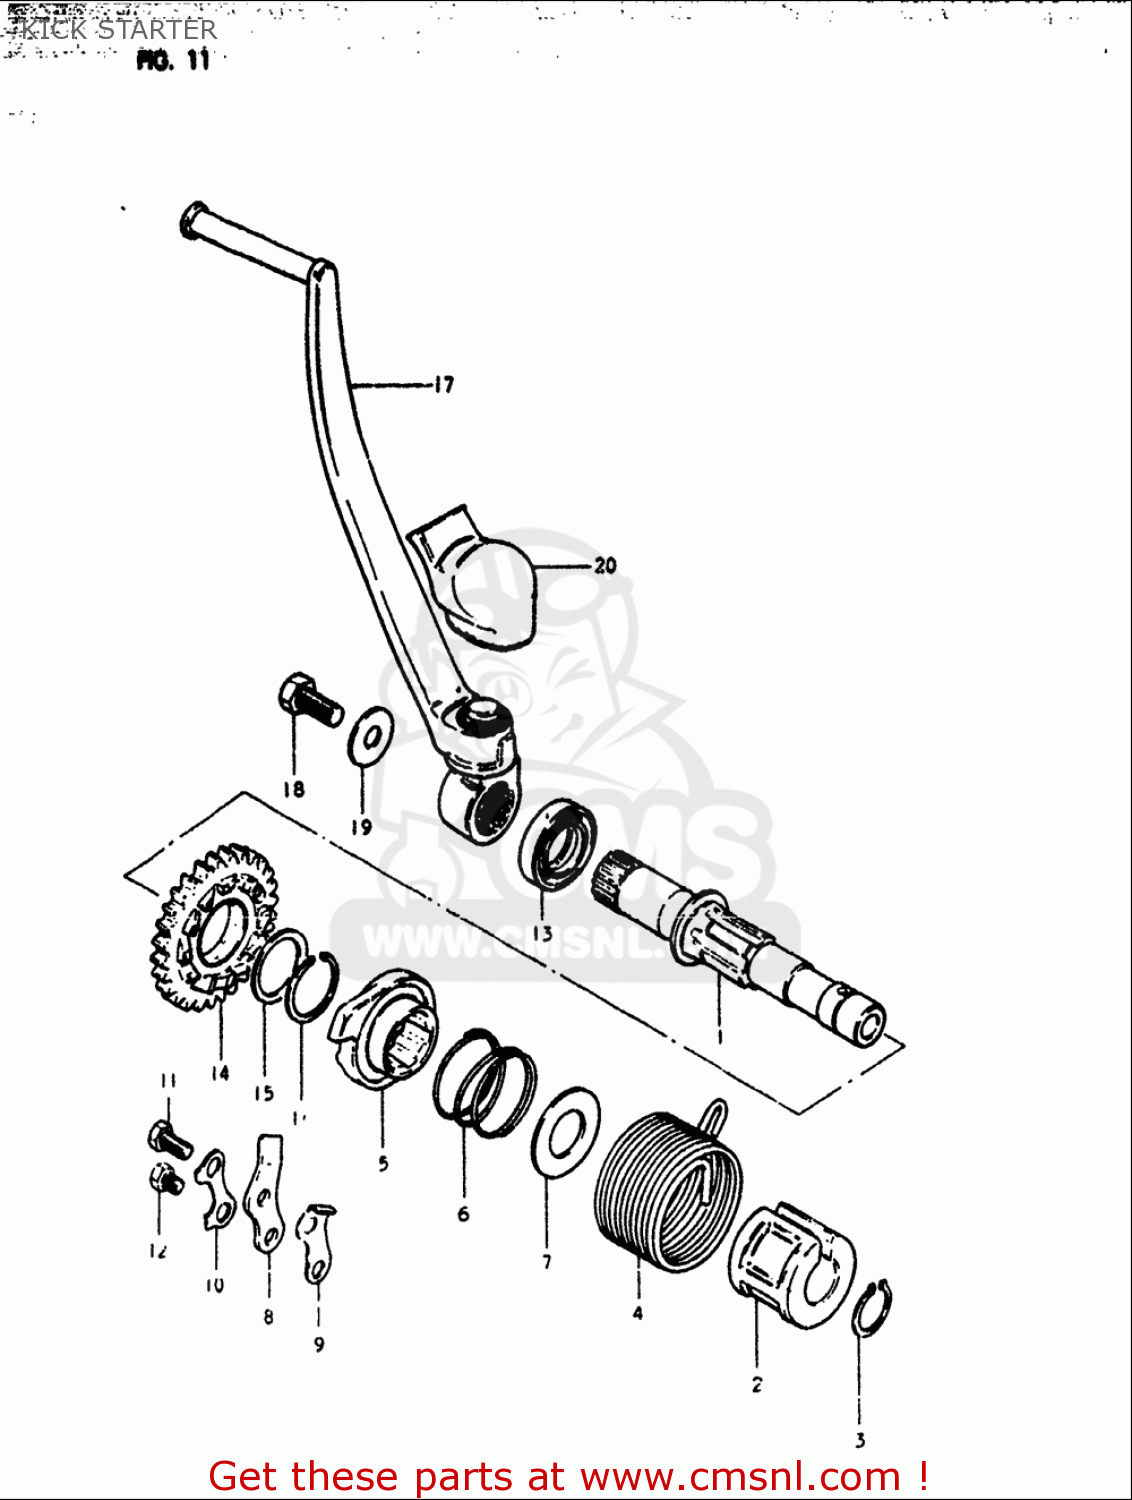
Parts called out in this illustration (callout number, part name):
1	SHAFT,KICK STARTER
2	GUIDE,KICK STARTER SFT SPRING
3	CIRCLIP
4	SPRING
5	STARTER,KICK
6	SPRING
7	WASHER
8	GUIDE,KICK STARTER
9	STOPPER,KICK STARTER
10	WASHER
11	BOLT
12	BOLT
13	BEARING(20X27X25)
14	GEAR,KICK STARTER DRIIVE
15	SHIM(22X28X1)
16	CIRCLIP
17	LEVER ASSY,KICK STARTER
18	BOLT
19	WASHER(8.2X23X3.2)
20	COVER,KICK STARTER LEVER JOINT
